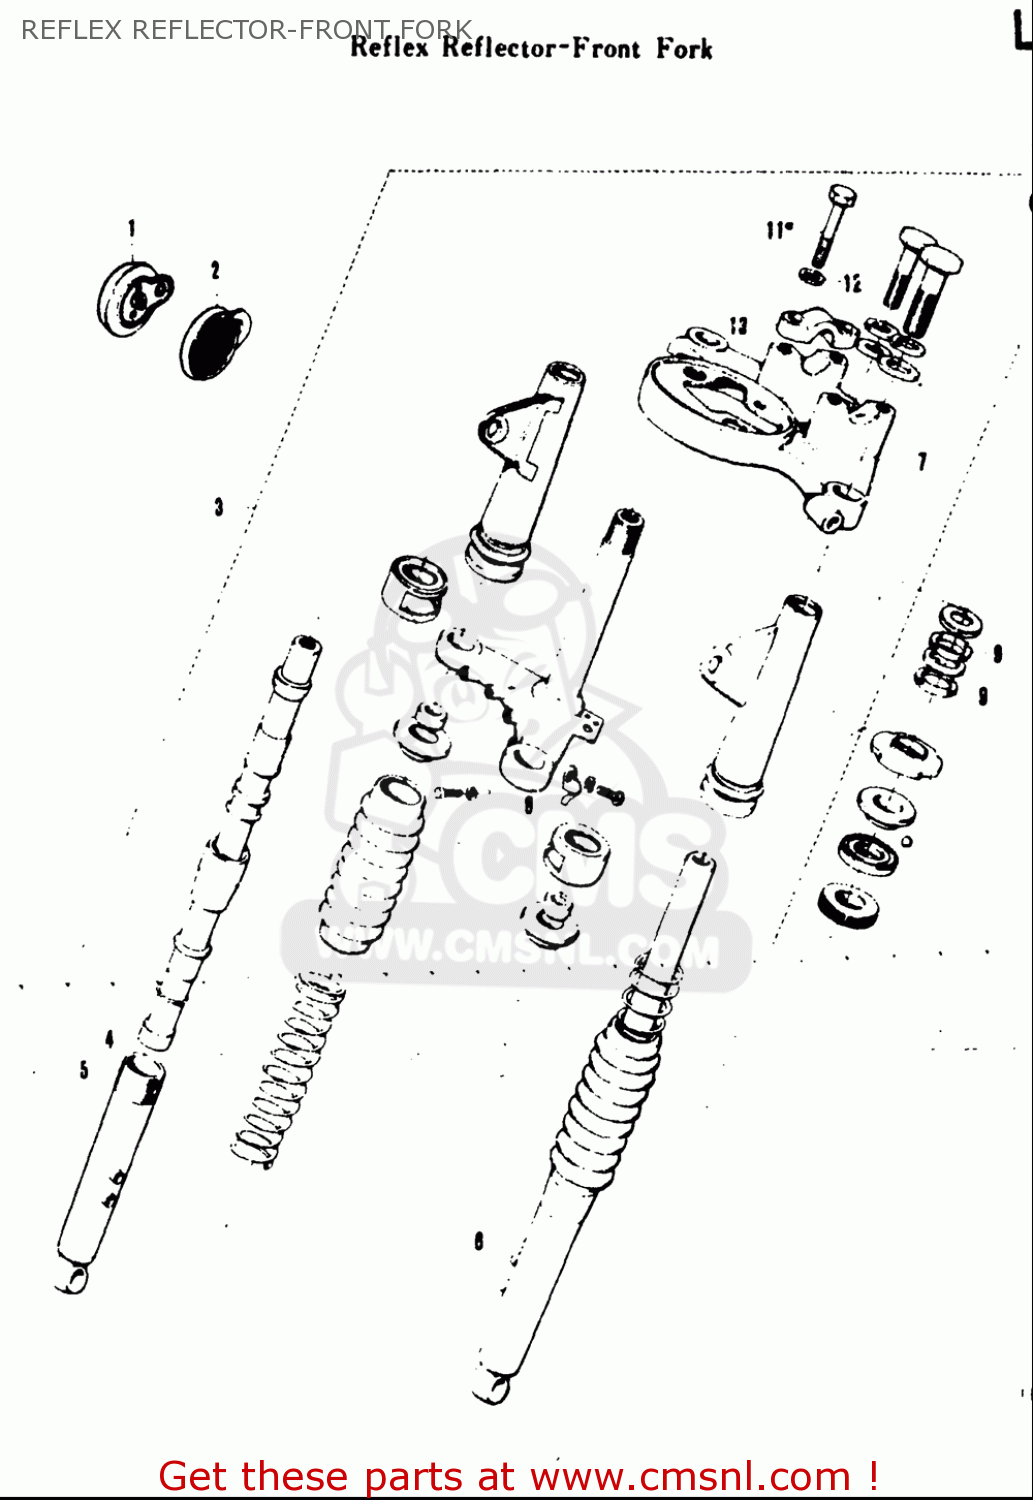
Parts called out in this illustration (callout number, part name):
8	CLIP,BRAKE CABLE
9	NUT
11	BOLT
